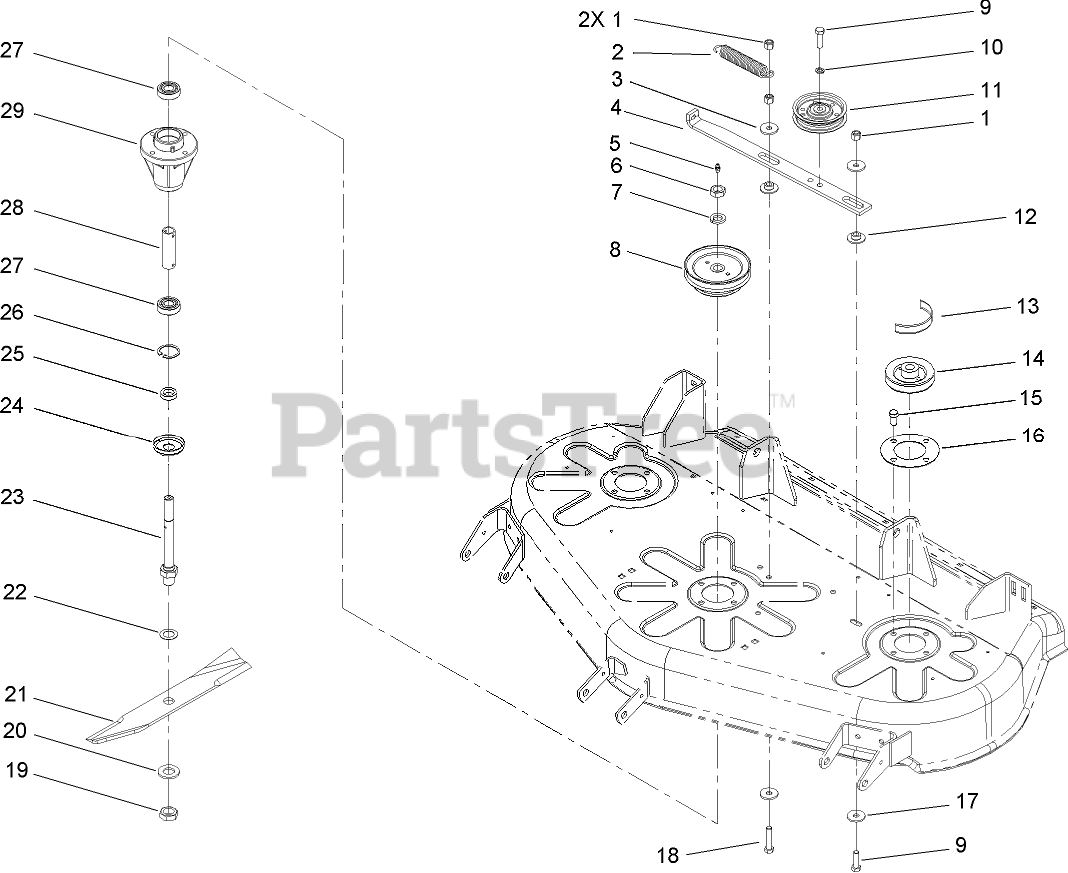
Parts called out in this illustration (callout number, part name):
1	NUT-LOCK, NI
2	SPRING-EXTENSION
3	WASHER
4	BAR-IDLER SUPPORT
5	FITTING-GREASE
6	NUT-JAM
7	WASHER-LOCK
8	PULLEY
9	SCREW-HH
10	WASHER-LOCK
11	PULLEY-IDLER, FLAT
12	SPACER-BUSHING
13	V-BELT
14	PULLEY
15	SCREW-HH
16	PLATE-SPINDLE
17	WASHER
18	SCREW-HH
19	NUT-JAM
20	WASHER-FLAT
21	BLADE-14.5IN
22	WASHER-FLAT
23	SHAFT-SPINDLE
24	CUP-SPINDLE
25	SPACER-BLADE
26	RING-RETAINING
27	BEARING-BALL
29	HOUSING-SPINDLE
